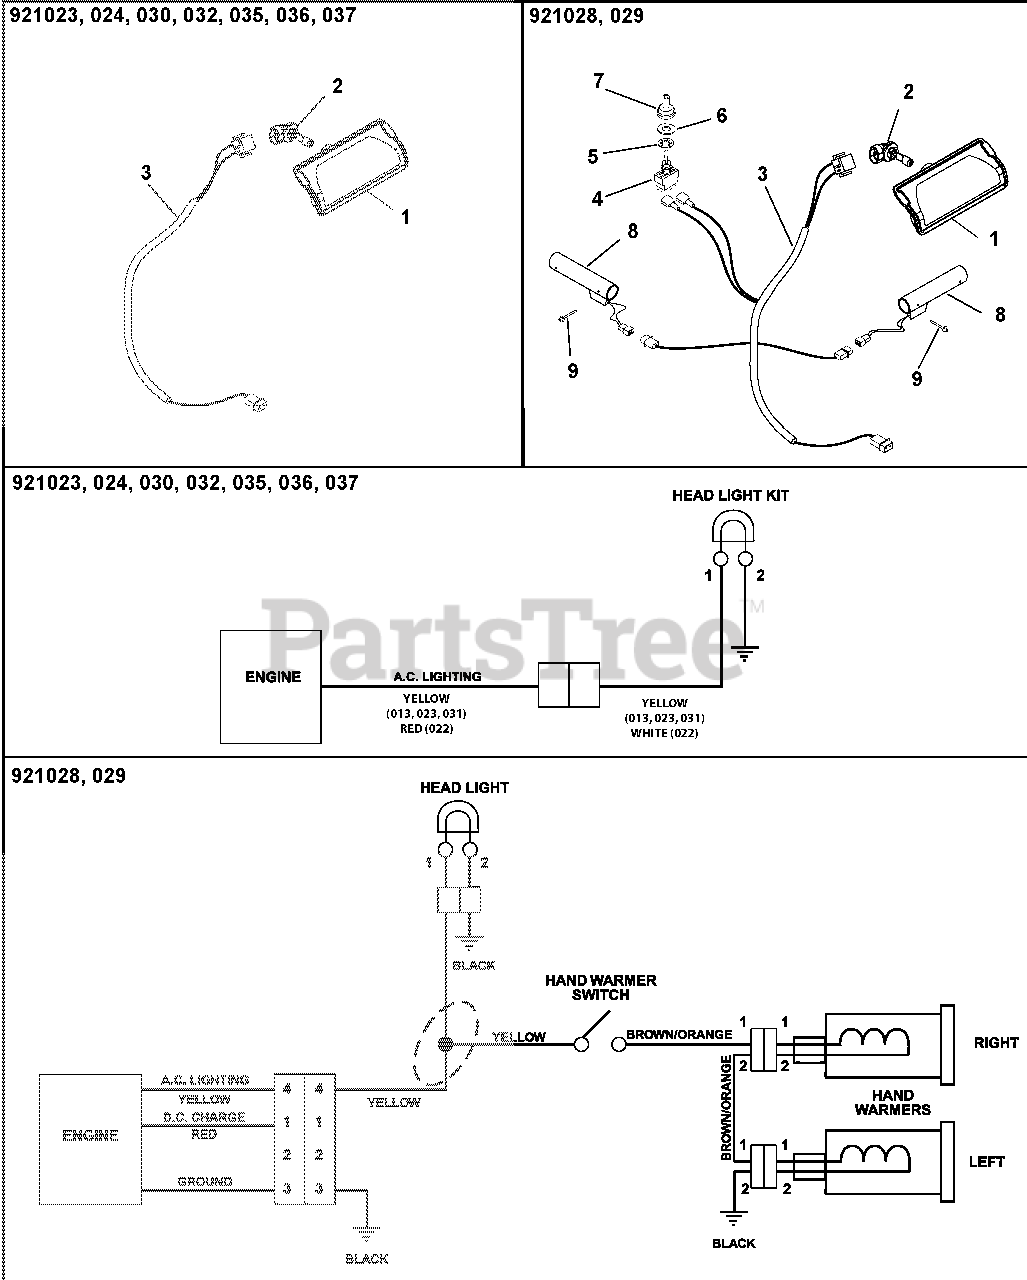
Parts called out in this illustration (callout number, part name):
1	HEADLIGHT ASSY, HALOGEN 20W
2	BULB, LIGHT-HALOGEN 20W
3	HARNESS, LIGHT & WARMER
4	SWITCH, ON/OFF
5	WSHR-LK-INT .563X.040 YWZC
6	WSHR-FL-STL .505X.875X.024 PL
7	BOOT, SWITCH
8	HEATED GRIP, MAGURA
9	RVT-POP #43 .125X.313 STL ZINC
